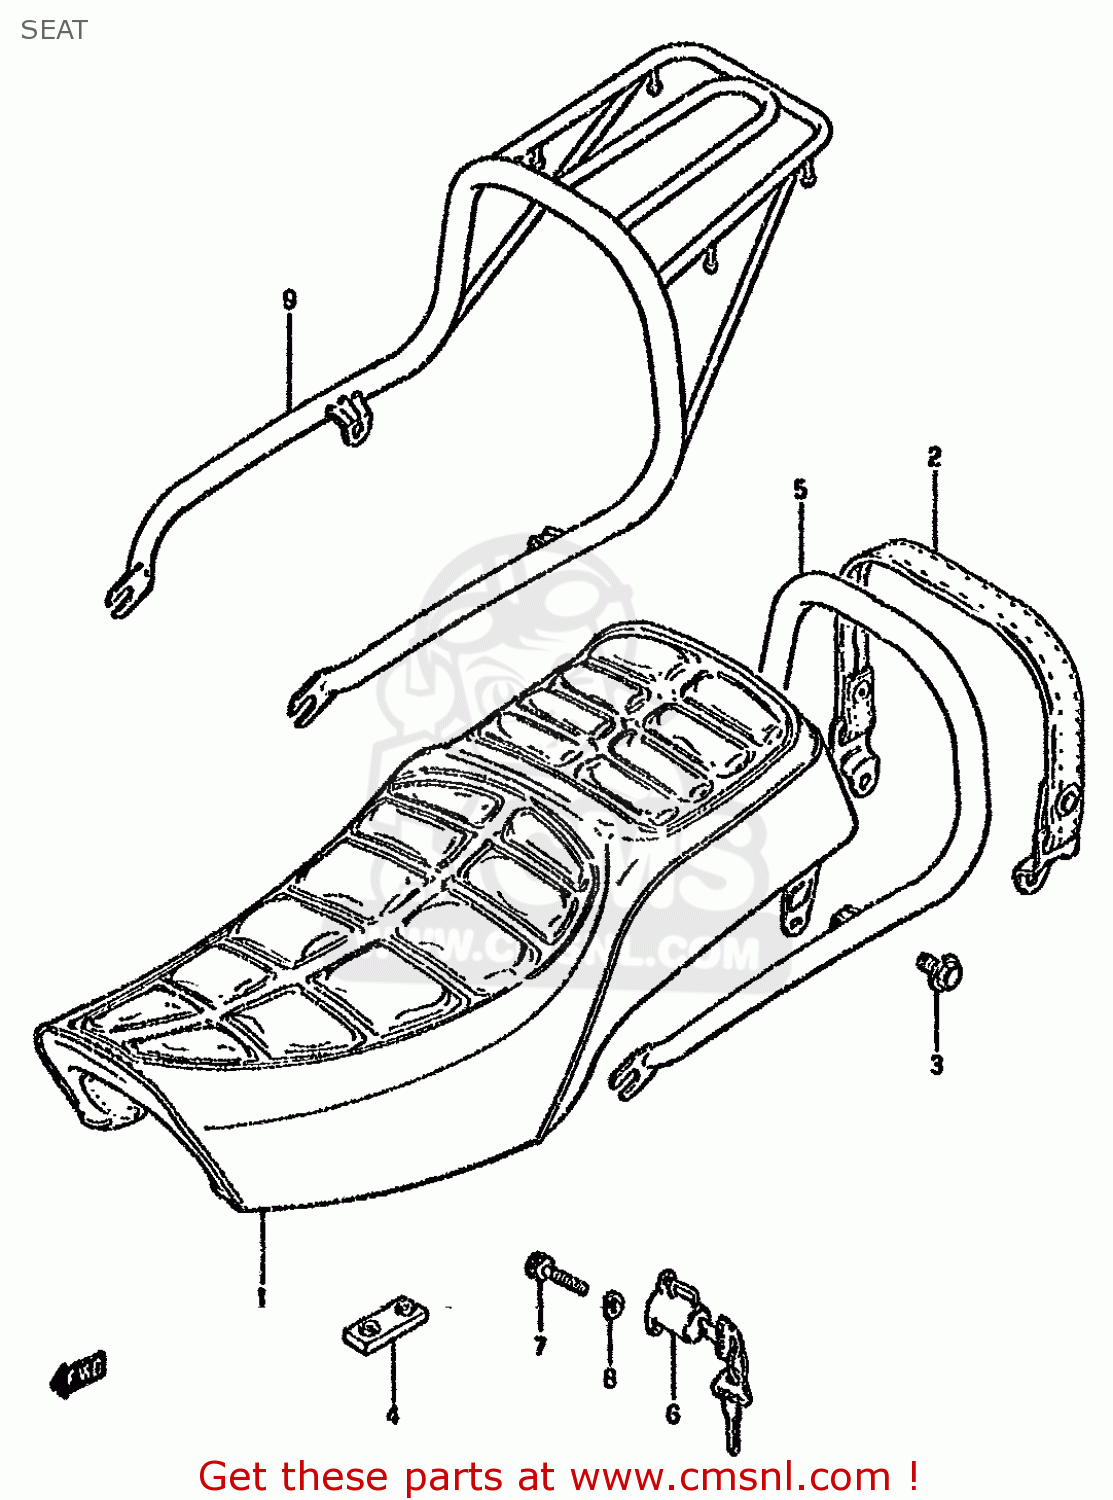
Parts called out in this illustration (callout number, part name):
1	SEAT ASSY
2	BAND,SEAT
3	BOLT
4	CUSHION
5	HANDLE,PILLION RIDER
6	LOCK SET,HELMET
7	SCREW
8	WASHER,LOCK
9	CARRIER
